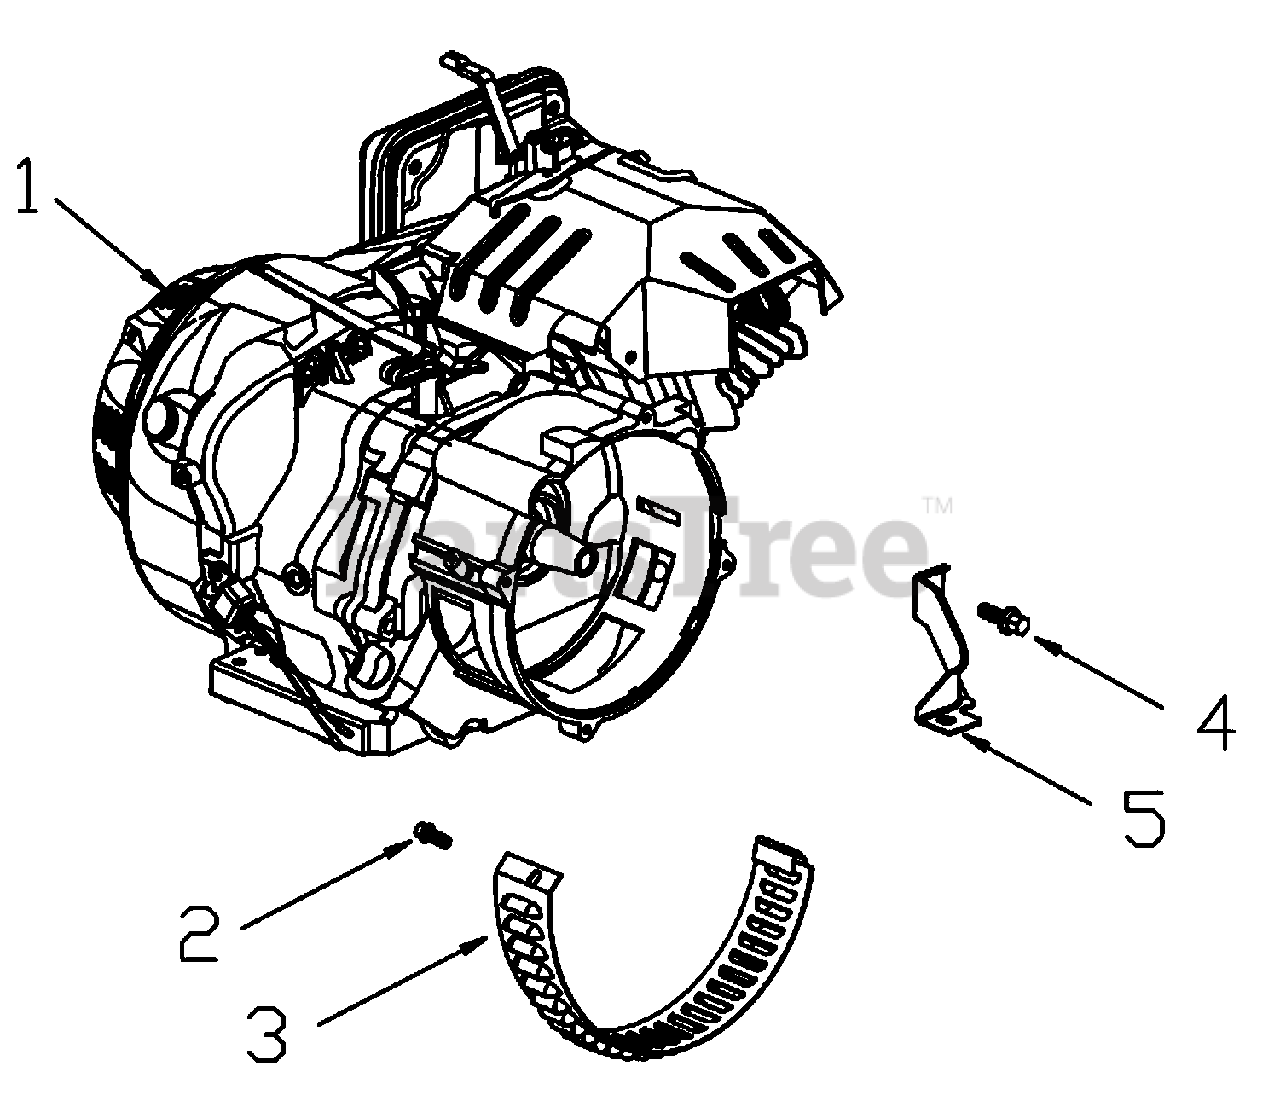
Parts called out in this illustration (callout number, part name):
1	ENGINE G390FA
2	BOLT, FLANGE M5*10
3	COVER, DUST
4	BOLT, FLANGE M6*12
5	BRACKET, AIR CLEANER
